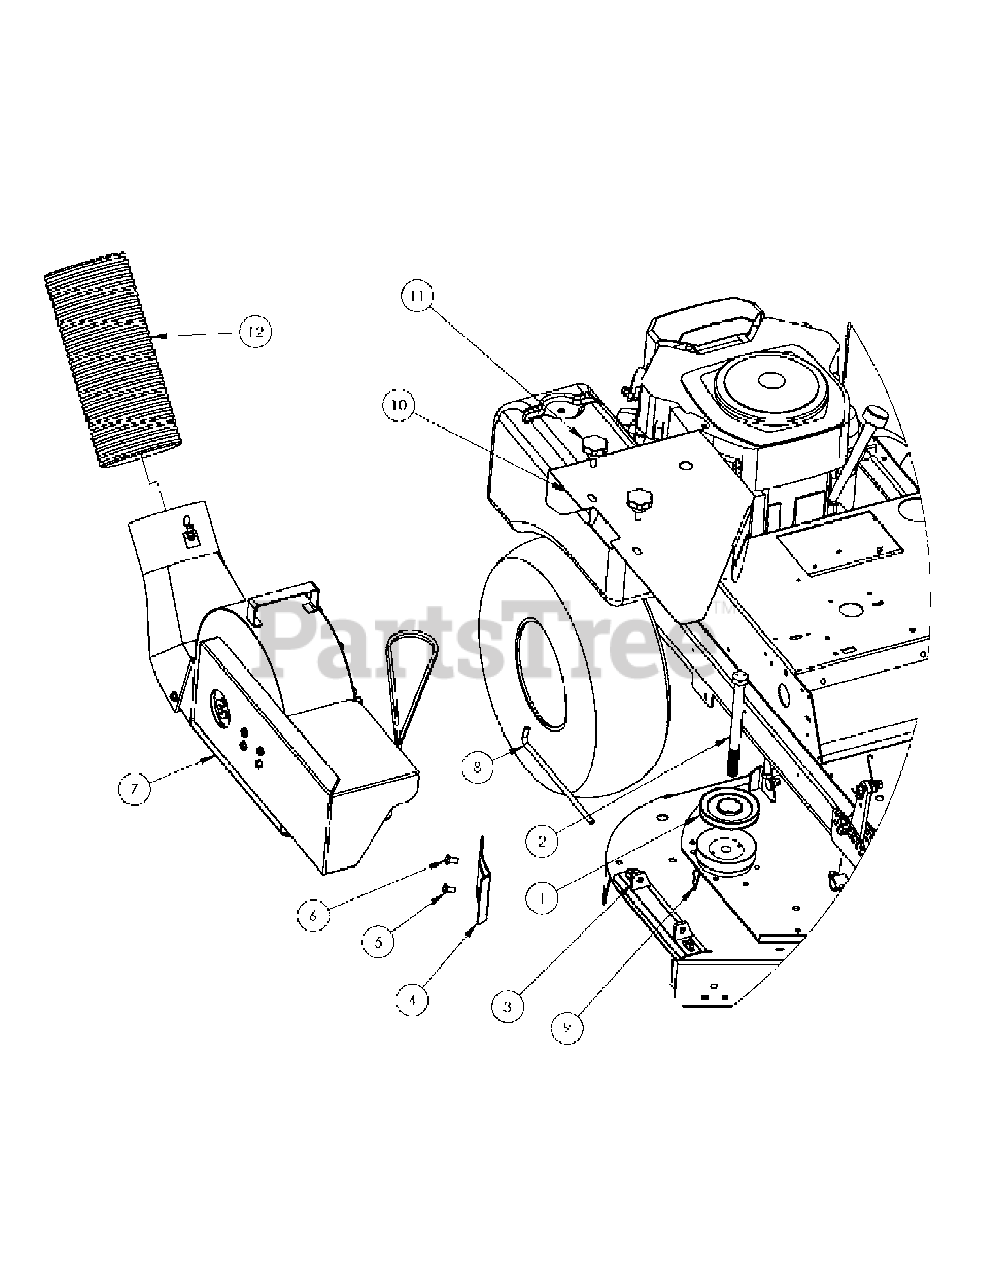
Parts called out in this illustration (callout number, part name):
1	BLOWER DRIVE PULLEY
3	DECK BRACKET
4	DECK SLIDE ADAPTOR
6	CARRAGE BOLT, 3/8" - 16 X 1" LONG
8	MOUNTING PIN
10	48" BELT GUARD
11	MOUNTING KNOBS
12	DISCHARGE HOSE
